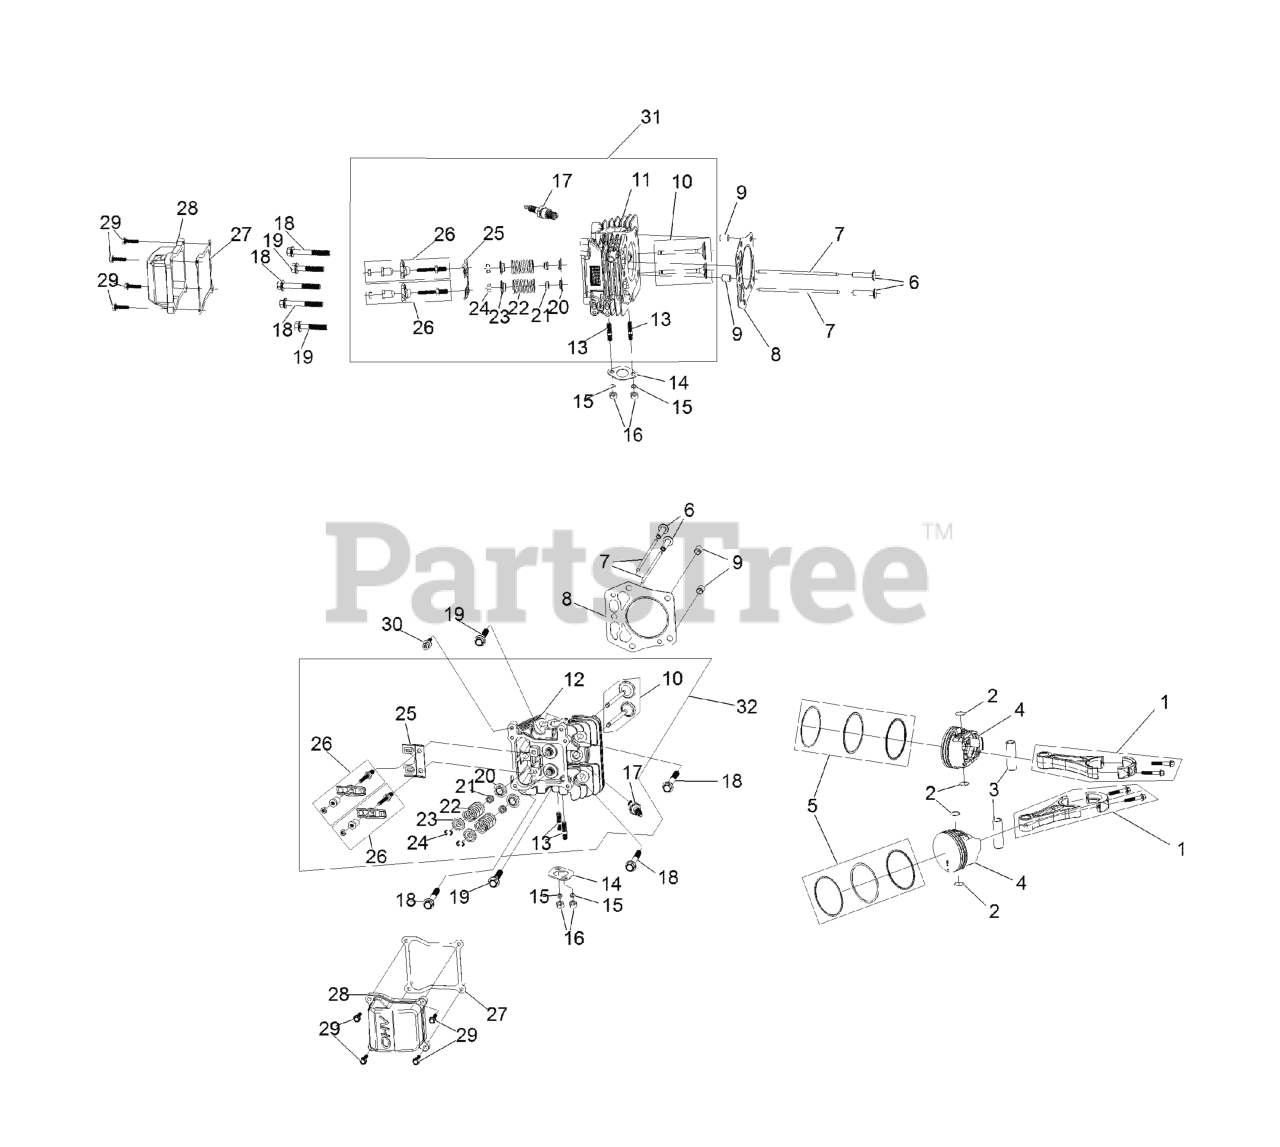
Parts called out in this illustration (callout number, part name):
1	CONNECTING ROD ASM
2	CLIP-PIN, PISTON
3	PIN-PISTON
5	PISTON RING SET
6	LIFTER-VALVE
7	ROD-PUSH
8	GASKET-HEAD, CYLINDER
9	PIN-DOWEL
10	VALVE SET
11	HEAD-CYLINDER, RIGHT
12	HEAD-CYLINDER, LEFT
13	STUD-EXHAUST
14	GASKET-EXHAUST
15	WASHER-LOCK, SPLIT
17	SPARK PLUG
18	SCREW-HWH
19	SCREW-HWH
20	SEAT-SPRING, VALVE
21	SEAL-STEM, VALVE
22	SPRING-VALVE
23	RETAINER-SPRING, VALVE
24	KEEPER-VALVE
25	PLATE-GUIDE, PUSH ROD
26	ROCKER ARM ASM
27	GASKET-VALVE COVER
28	COVER-VALVE
29	SCREW-HHF
30	SCREW-SHOULDER, HH
31	COMPLETE RIGHT HEAD ASM
32	COMPLETE LEFT HEAD ASM
